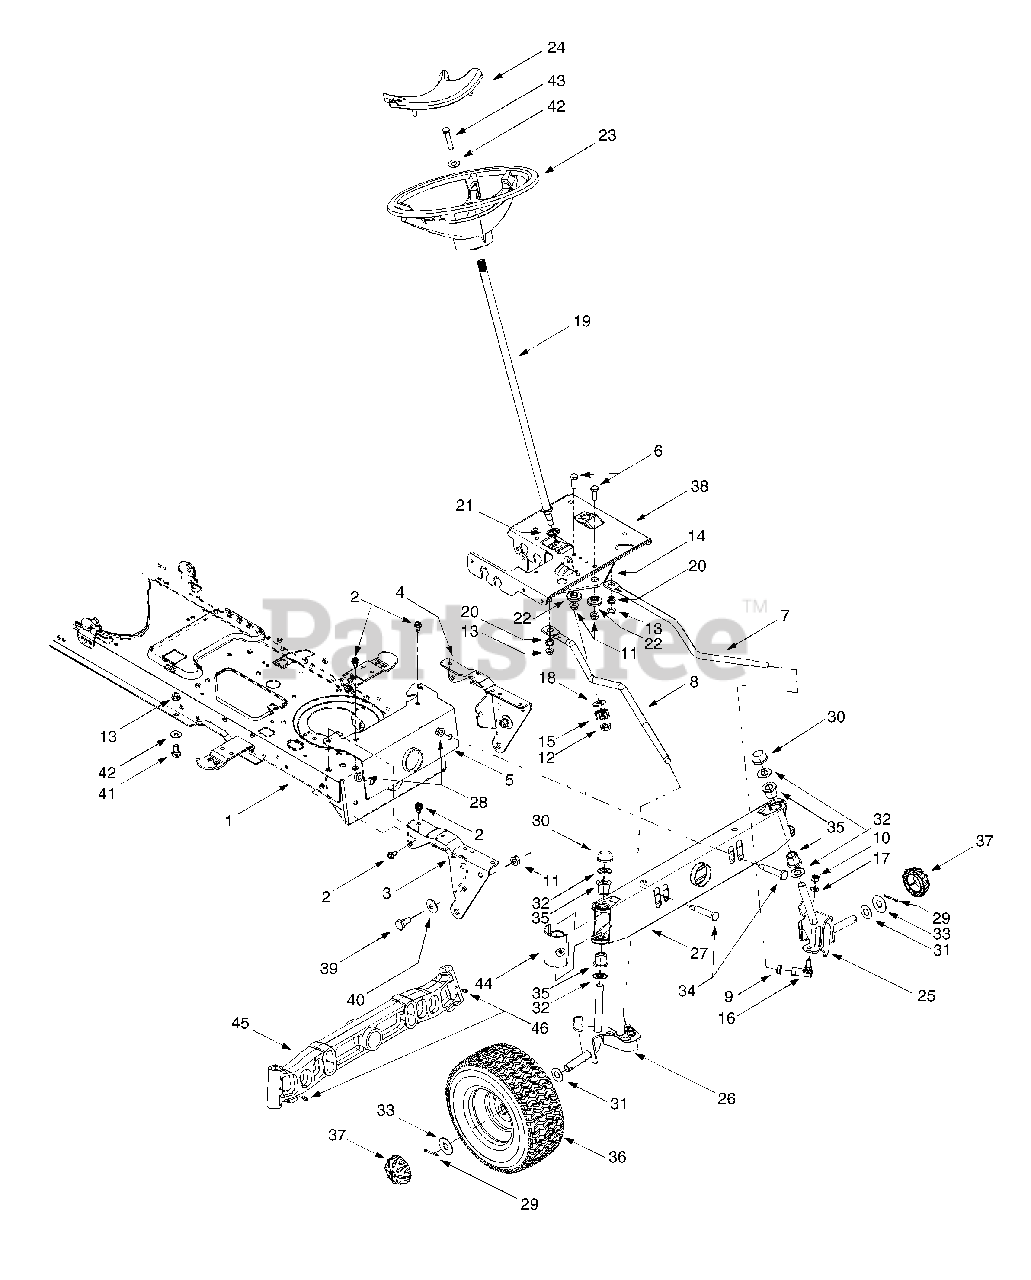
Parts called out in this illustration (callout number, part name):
6	Hex Cap Screw, 3/8-16 x 1 (Grade 5)
7	LH Drag Link
8	RH Drag Link
9	Jam Nut, 7/16-20 (Grade 2)
10	Hex Nut, 3/8-24 (Grade 2)
11	Flange Lock Nut, 3/8-16
12	Flange Lock Nut, 7/16-20
13	Flange Lock Nut, 5/16-18
14	Steering Gear, 11/90 Ratio
15	Steering Pinion Gear
16	Ball Joint, 7/16-20
17	Lock Washer, 3/8
18	Flat Washer, .51 x 1.12 x .06
19	Steering Shaft, .625 OD x 24.4
20	Plastic Bushing, .38 ID
21	Hex Flange Bearing, 5/8
22	Shoulder Spacer, .38 ID
23	Steering Wheel
24	Steering Wheel Cap w/ Icon
25	LH Axle Assembly, .625 Diameter
25	LH Axle Assembly, .625 / .750 Diameter
26	RH Axle Assembly, .625 Diameter
26	RH Axle Assembly, .625 / .750 Diameter
28	Flange Lock Nut, 3/8-16
29	Cotter Pin
30	Push Cap, .625
30	Push Cap, .750
31	Flat Washer, .64 x 1.0 x .12
32	Flat Washer, .64 x 1.24 x .06
32	Flat Washer, .78 x 1.59 x .06
33	Flat Washer, .635 x 1.589 x .06
34	Shoulder Screw, .5 x 2.2, 3/8-16
35	Flange Bearing, .632 ID x .937 OD
35	Flange Bearing, .760 ID x .937 OD
37	Hub Cap
39	Shoulder Screw, 3/8-16
40	Bell Washer, .39 x 1.13 x .062
41	Shoulder Screw, .435 x .178, 5/16 x .56
42	Bell Washer, .34 x .872
43	Hex Bolt, 5/16-18 X 1
44	Pivot Bar End Cap
45	Cast Iron Pivot Bar
46	Lube Fitting, 3/16
